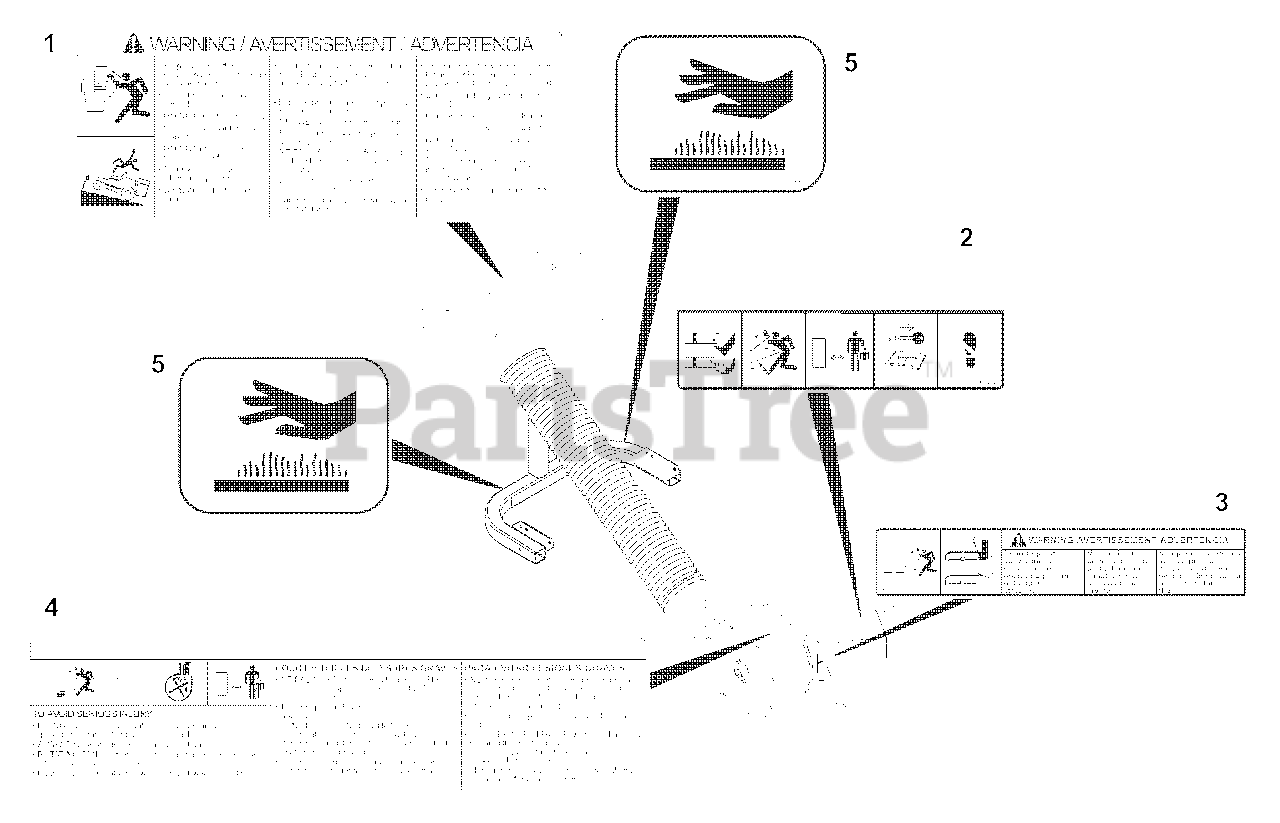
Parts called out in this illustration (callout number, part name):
1	Decal-Warning, Bagger Cover
2	Decal, Mower Pan Head Danger
3	Decal, Warning
4	Decal-Caution, Grass Pump
5	Decal, Hot Surface
